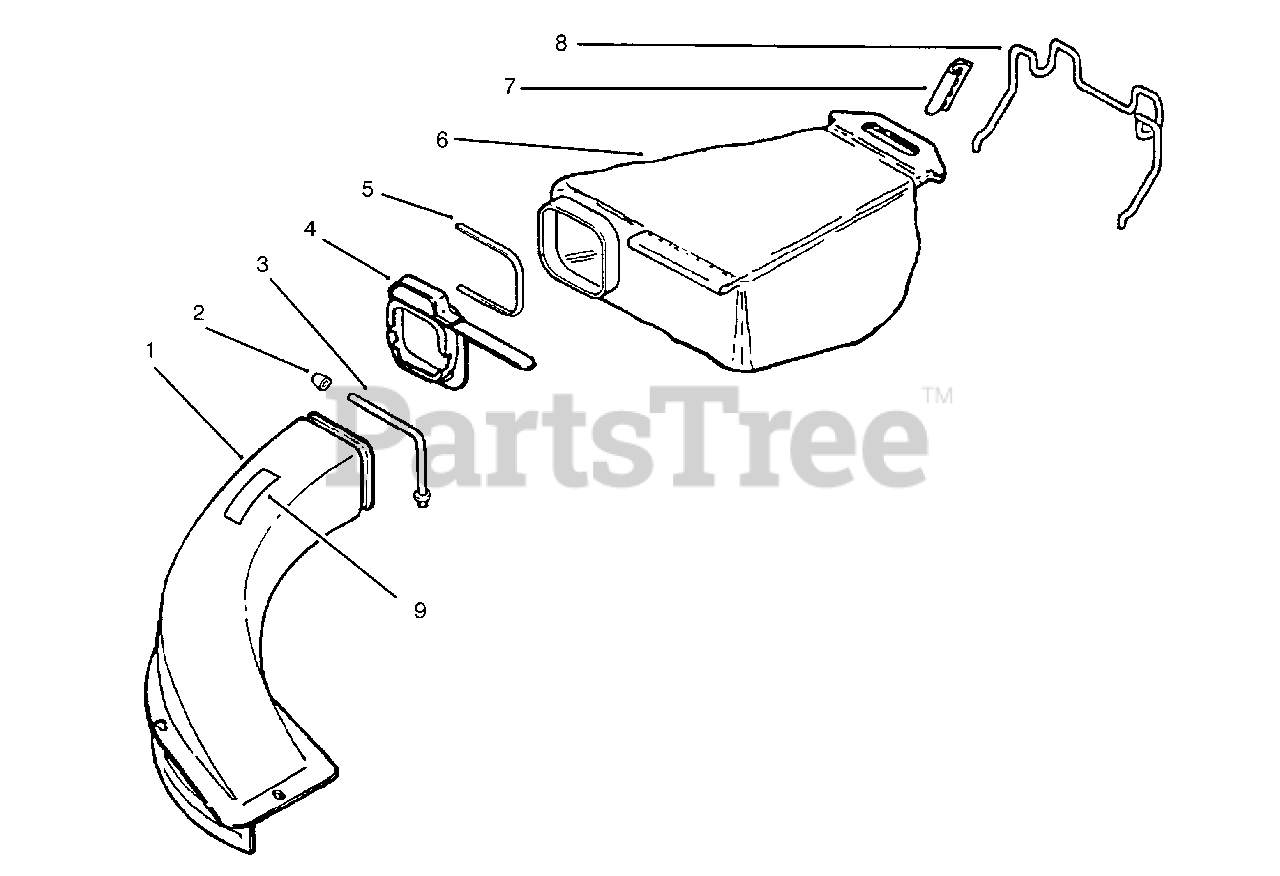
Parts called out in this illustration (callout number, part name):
1	Chute & Support Assy (Incl. Ref.# 2,3 & 9)
2	Nut-Cap
3	Chute Support
4	Adaptor Assembly
5	Tie Strap
6	Bag Assembly (Inc. Ref.#4-6)
7	Hanger Clamp
8	Wide Hanger
9	Decal-Danger
